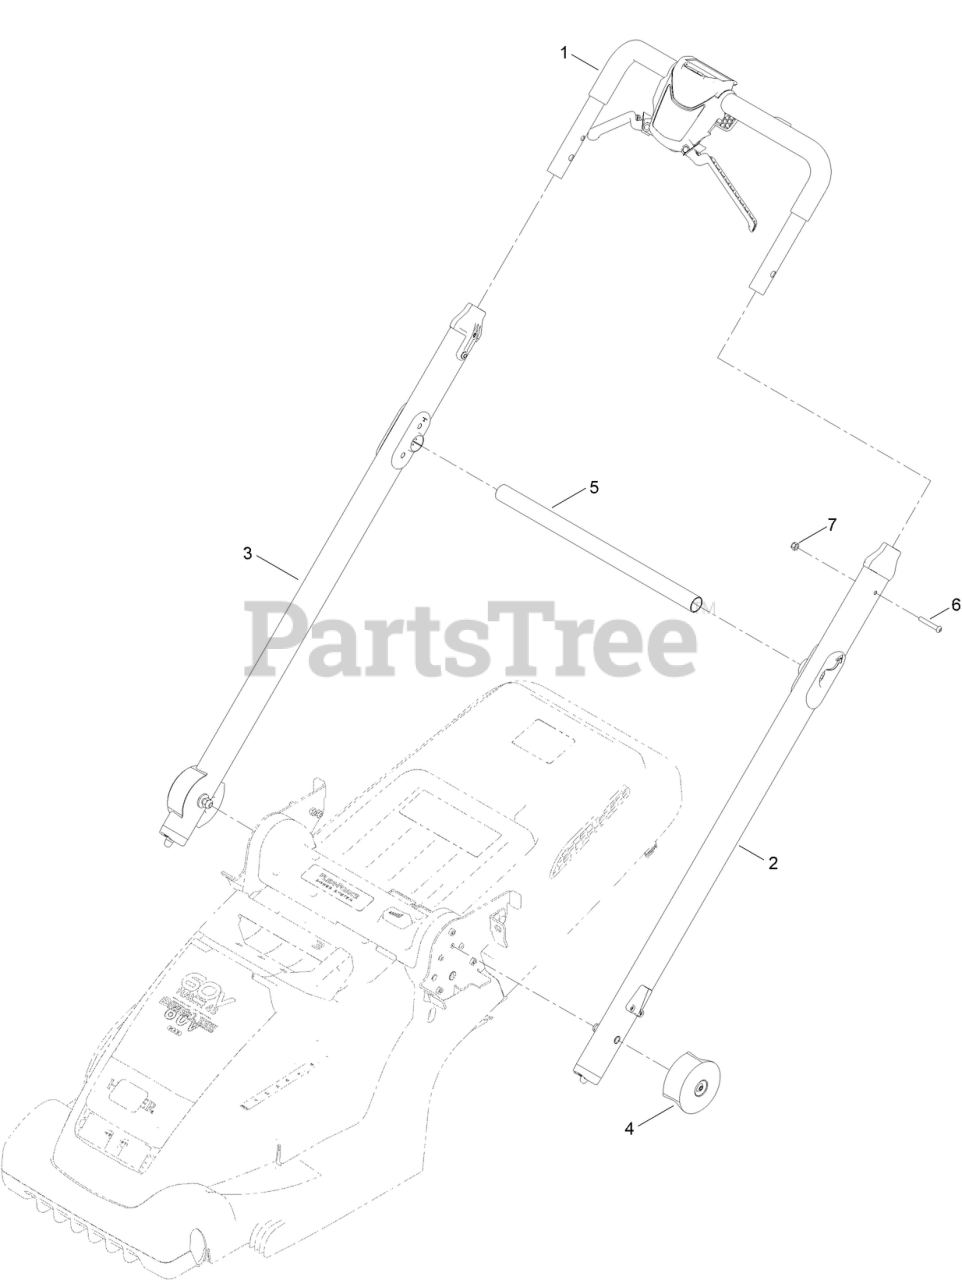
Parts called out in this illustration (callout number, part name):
1	CONTROL LEVER ASM, PROPELLED
2	HANDLEBAR ASM, LH
3	HANDLEBAR ASM, RH
4	HANDLEBAR END CAP
5	BRACE, HANDLEBAR RELEASE
6	BOLT, M6X40
7	NUT, NYLOC, M6X1
